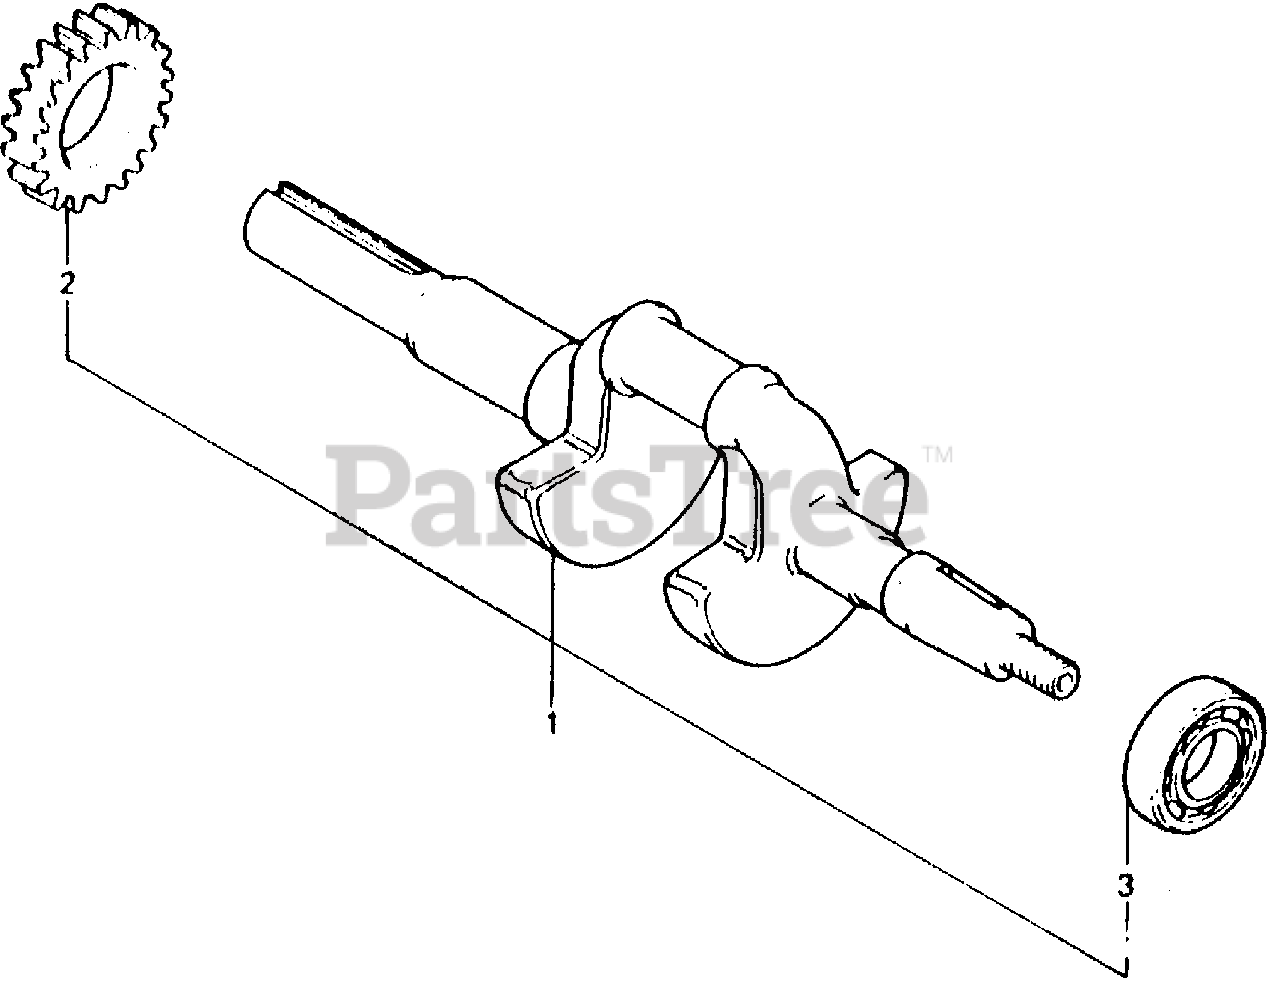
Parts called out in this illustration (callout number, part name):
1	CRANKSHAFT (S-TYPE)
2	GEAR, TIMING
3	BEARING, RADIAL BALL (6205)
